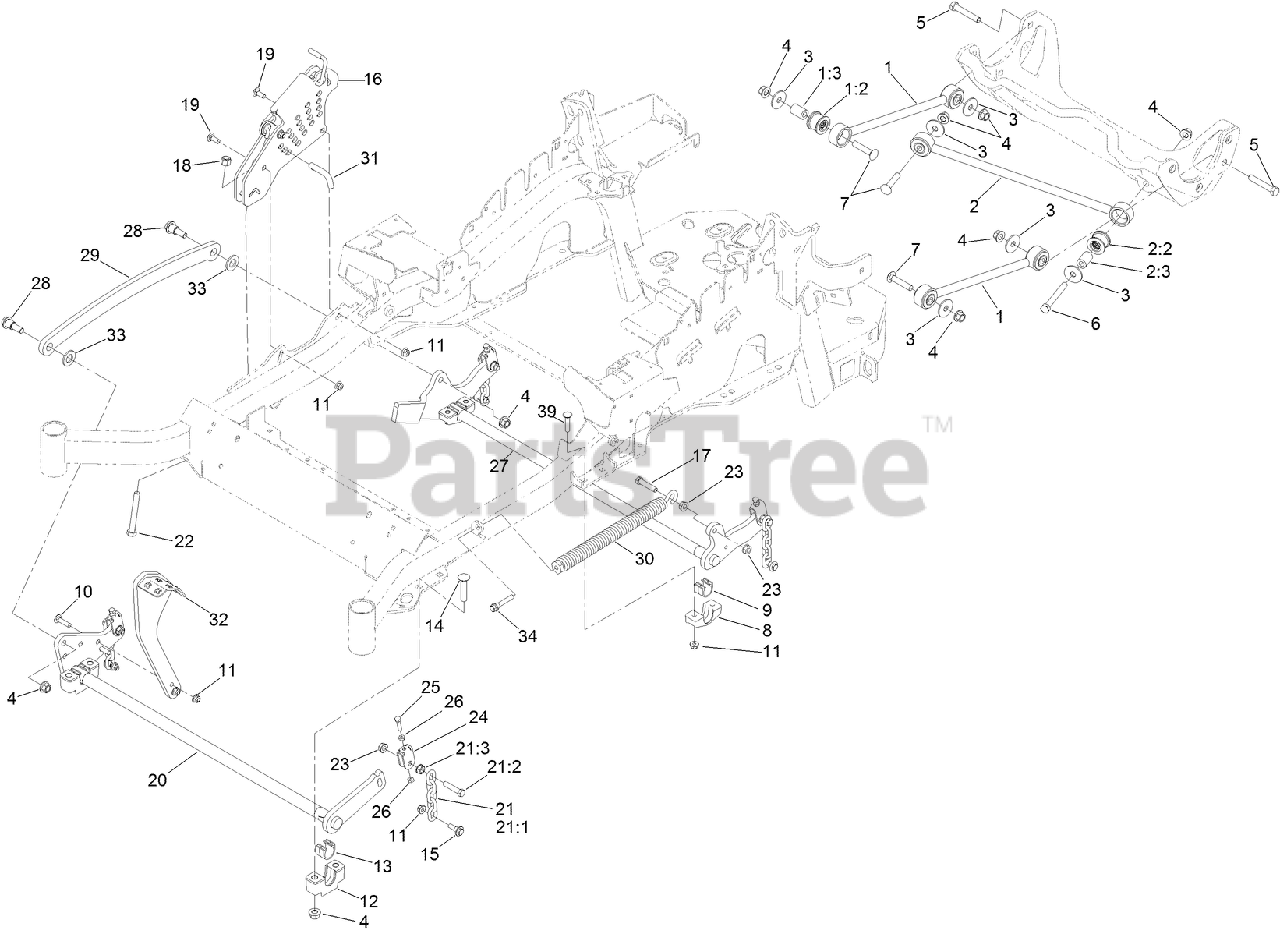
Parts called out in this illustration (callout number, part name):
1	DECK STRUT ASM
1:2	BUSHING-SUSPENSION, RUBBER
1:3	SPACER
2	PANHARD ROD ASM
2:2	BUSHING-SUSPENSION, RUBBER
2:3	SPACER
3	WASHER-THRUST
4	NUT-LOCK
5	SCREW-HH
6	SCREW-HH
7	SCREW-CARR
8	SUPPORT-CROSS SHAFT, REAR BEARING
9	BEARING-CROSS SHAFT, REAR
10	SCREW-CARR
11	NUT-HF, NI
12	SUPPORT-CROSS SHAFT, BEARING
13	BEARING-CROSS SHAFT, FRONT
14	BOLT-CARR
15	SCREW-SHOULDER, HHF
16	HOC ASM
17	SCREW-HH
18	NUT-LOCK, NI
19	BOLT-CARR
20	DECKLIFT-FRONT
21	DECK LIFT CHAIN ASM
21:1	CHAIN-LIFT, DECK
21:2	SCREW-HH
21:3	NUT-HF
22	BOLT-TAP
23	NUT-HF
24	YOKE-ADJUST, DECK
25	SCREW-HH
26	NUT-JAM
27	LIFT-DECK, REAR
28	SCREW-SHOULDER, HHF
29	LINK-LIFT, DECK
30	SPRING-EXTENSION
31	PIN-HOC
32	LEVER-FOOT
33	WASHER-FLAT
34	BOLT-SHOULDER
39	SCREW-CARR
